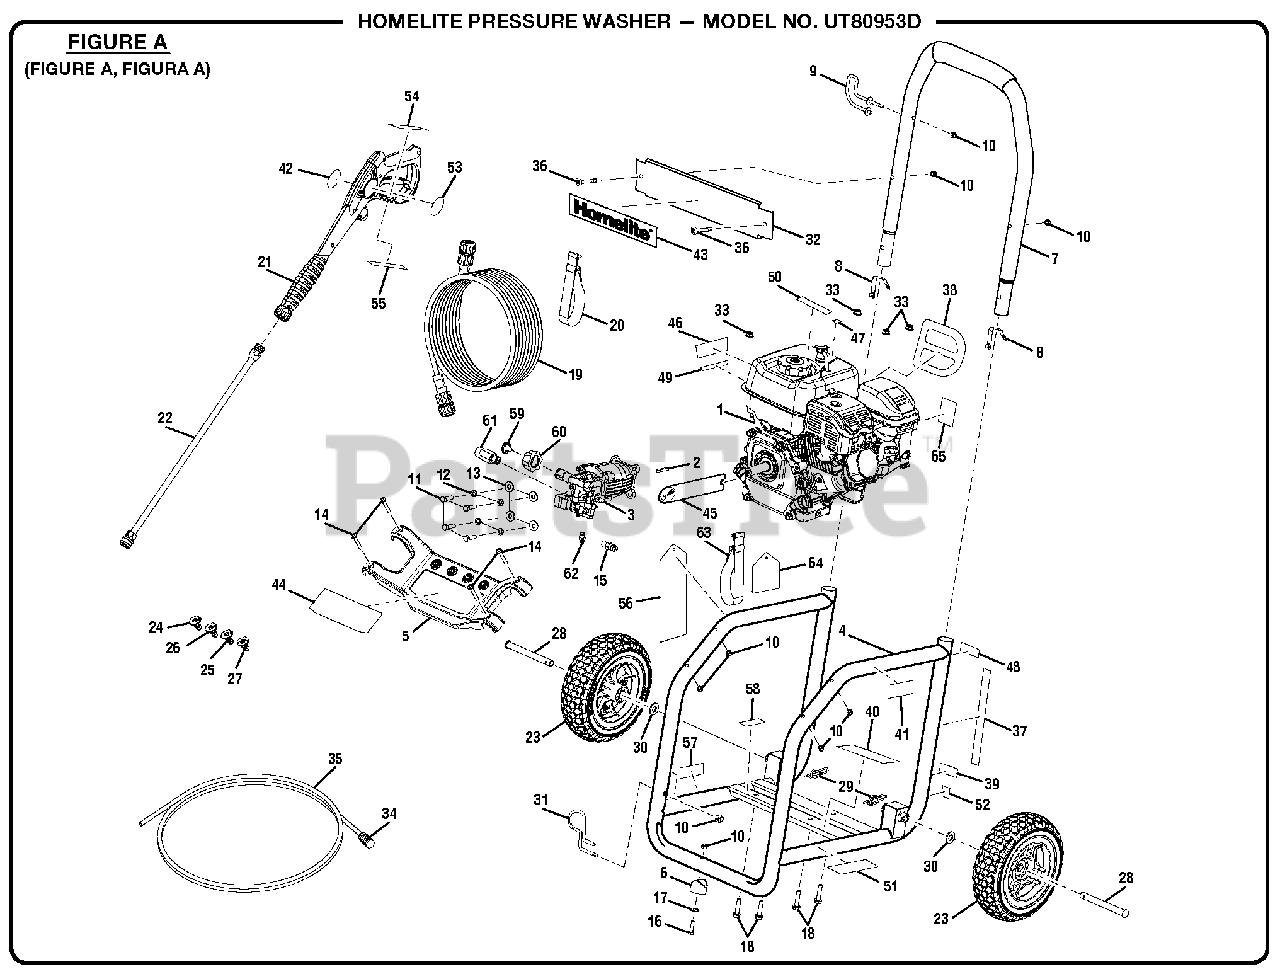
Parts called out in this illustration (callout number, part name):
1	Engine (RATO 180cc)
2	Output Shaft Key (3/16 x 40 mm)
4	Main Frame
5	Nozzle Holder
6	Rubber Foot
7	Handle Assembly
8	Lock Button w/Spring Clip
9	Wand Holder (Upper)
10	Lock Nut (1/4-20)
11	Bolt (5/16-24 x 27 mm, Hex Hd)
12	Lock Washer (5/16 in)
13	Washer (5/16 in)
14	Screw (1/4-20 x 20 in, Torx)
15	Thermal Release Valve
16	Bolt (1/4-20 x 1-1/4 in)
17	Washer (1/4 in)
18	Bolt (M8 x 40 mm, Hex Flange Hd)
20	Hook and Loop Strap
21	Trigger Handle
22	Extension Wand
23	Wheel Assembly (10 in x 3 in)
24	Nozzle, 0deg
25	Nozzle 40deg
26	Nozzle 25deg
27	Soap Nozzle
29	Hitch Pin
30	Washer (1/2 in)
31	Wand Holder (Lower)
32	Front Panel
33	Lock Nut (M8 x 125)
35	Chemical Siphon Tube
36	Screw (1/4-20 x 157 in, Torx T-30)
37	Quick Start Label
38	Recoil Label
39	Choke Label
40	Data Label
41	Hot Surface Label
42	Trigger Handle Logo Label
43	Homelite Label
44	Performance Label
45	Add Oil Label
46	Danger Label
47	E85 Label
48	Homelite Inquiries Label
49	EMC Compliance Label
50	No Oil to Gas Label
51	Combustion Label
52	Fuel Label
53	Trigger Handle Warning Label (French and Spanish)
54	Warning Label
55	Wand Label (Max Rating)
56	Danger Hangtag
57	Lubricant Label
58	Dip Stick Label
59	Filter Screen
60	Inlet Tube
61	Outlet Tube
62	Detergent Suction Kit
63	Hook and Loop Strap
64	Nozzle Instructions Hangtag
65	Engine Label (On-Off)
